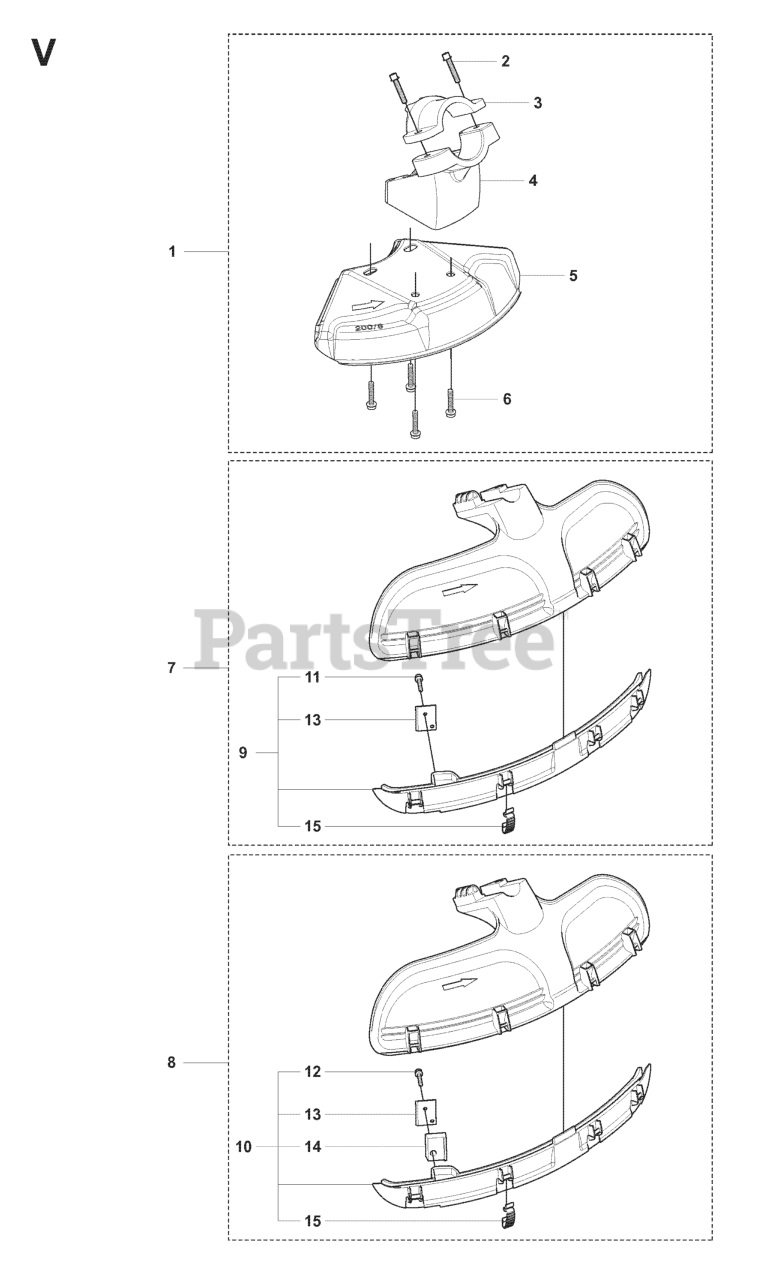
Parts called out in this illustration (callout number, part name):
1	%PROTECTOR
5	RP BLADE GUARD
7	COMBI PROTECTOR
8	SPLASH GUARD
10	LINE CUTTER
12	COMBI PROTECTOR
13	SPLASH GUARD
15	LINE CUTTER
16	DISTANSBLOCK
